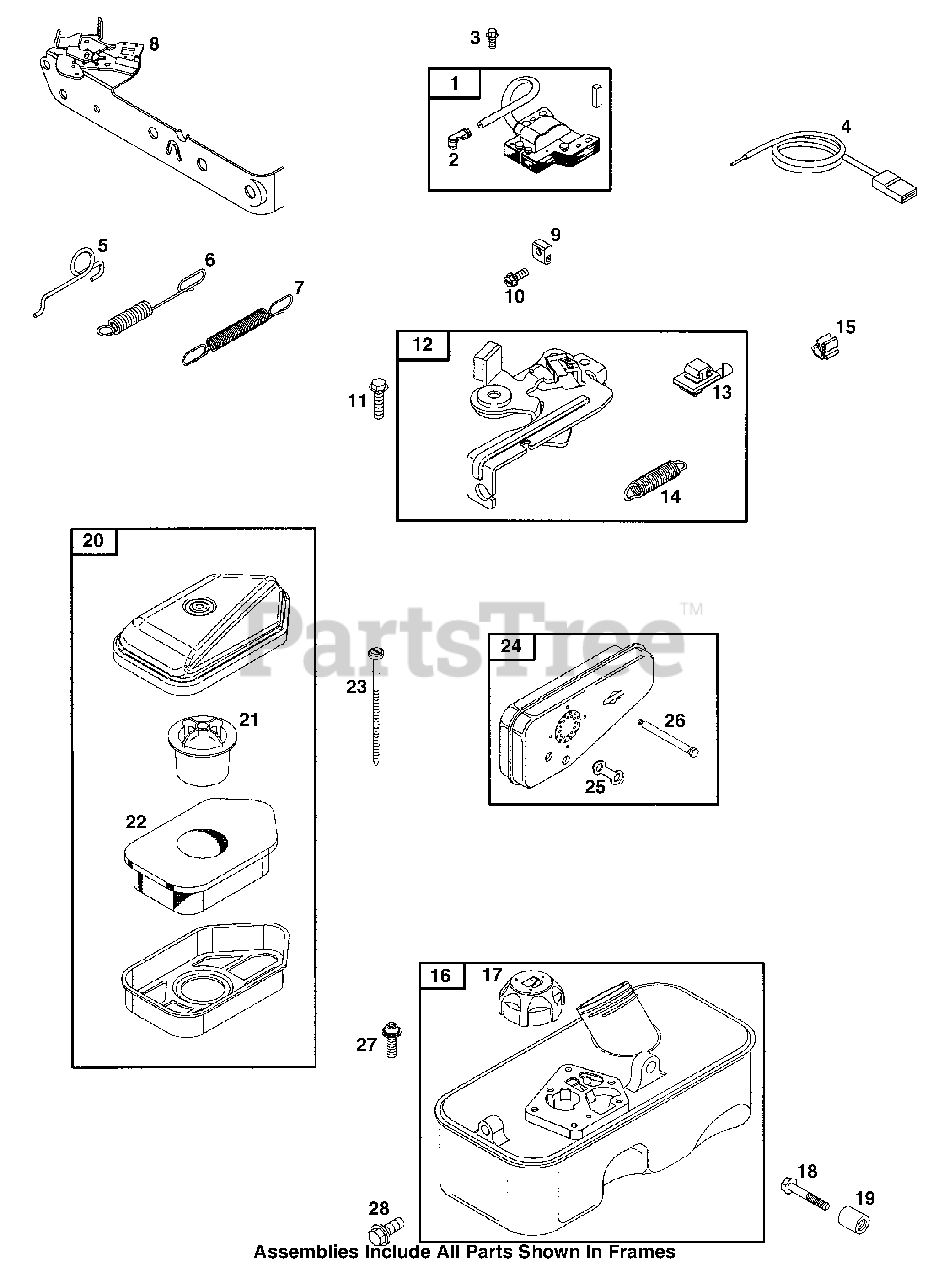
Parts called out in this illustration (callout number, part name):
1	Magneto Armature
2	Cable Terminal
3	Hex Screw
4	Stop Wire
5	Air Vane Link
6	Governor Spring
7	Governor Idler Spring
8	Control Bracket
9	Casing Clamp
10	Slotted Hex Screw
11	Hex Screw
13	Stop Switch
14	Brake Spring
17	Fuel Tank Cap
18	Hex Screw
19	Fuel Tank Spacer
20	Air Cleaner
21	Air Filter Retainer
22	A/C Foam Filter
23	Slotted Screw
24	Exhaust Muffler
25	Muffler Screw Lock
26	Shoulder Screw
27	Torx Screw
28	Hex Screw
